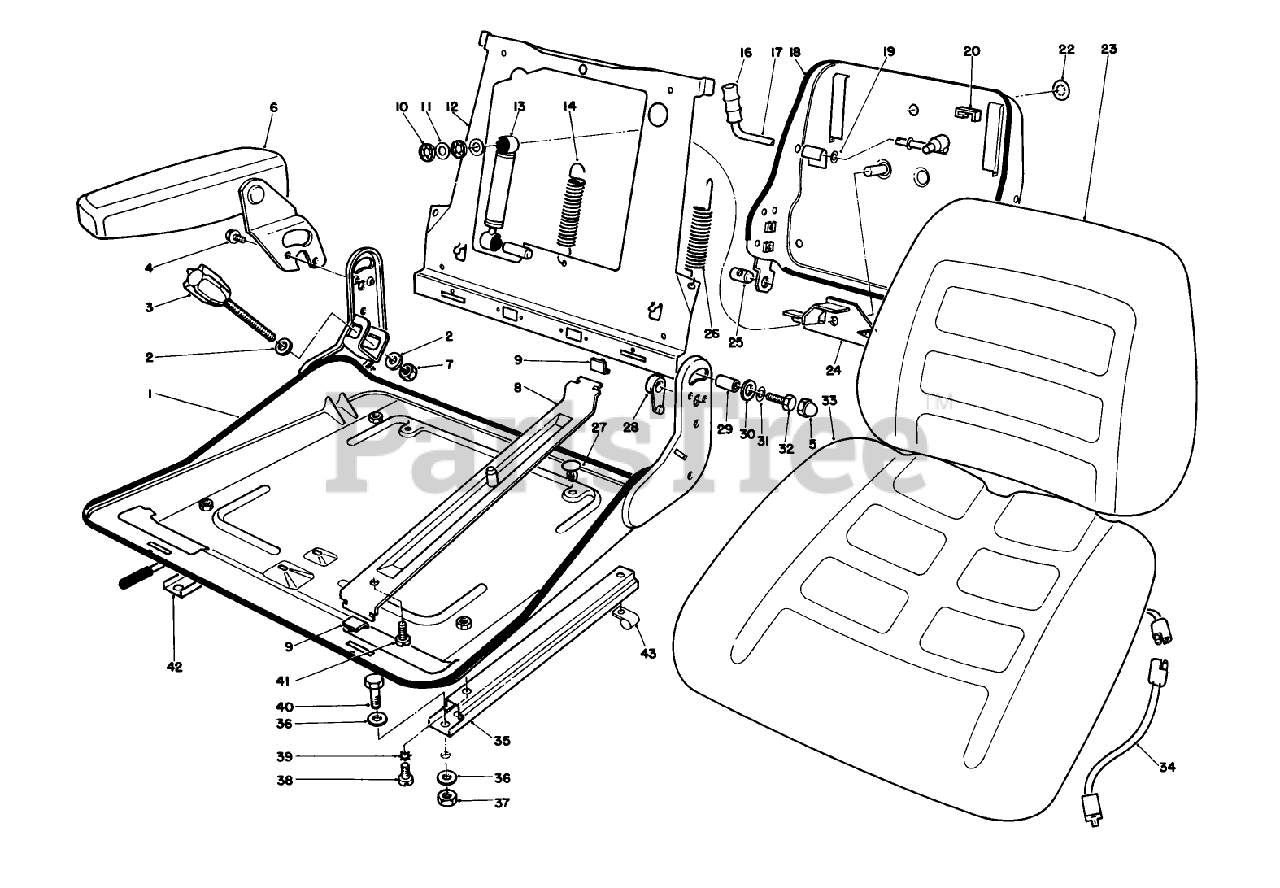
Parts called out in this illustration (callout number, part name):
1	Platform-Seat
2	WASHER
4	SCREW
5	COVER
6	RH ARMREST ASM
8	Carrier-Seat
10	CLAMP
11	Washer-Flat
12	Back Plate
13	SHOCK ABSORBER
14	SPRING
16	Cover-Grip
17	LEVER
18	Cover-Seat Back
19	WASHER
20	BUMPER
22	COVER
23	Cushion-Seat Back
24	LEVER
26	SPRING
28	SPACER
29	BUSHING
30	WASHER
31	WASHER
32	SCREW
33	CUSHION
34	JUMPER WIRE ASM
35	Bottom Rail Assembly L.H.
36	WASHER-PLAIN
37	NUT-LOCK, NI
38	SCREW
39	WASHER
40	SCREW-HH
41	SCREW
42	Bottom Rail Assy. R.H.
43	CLAMP
